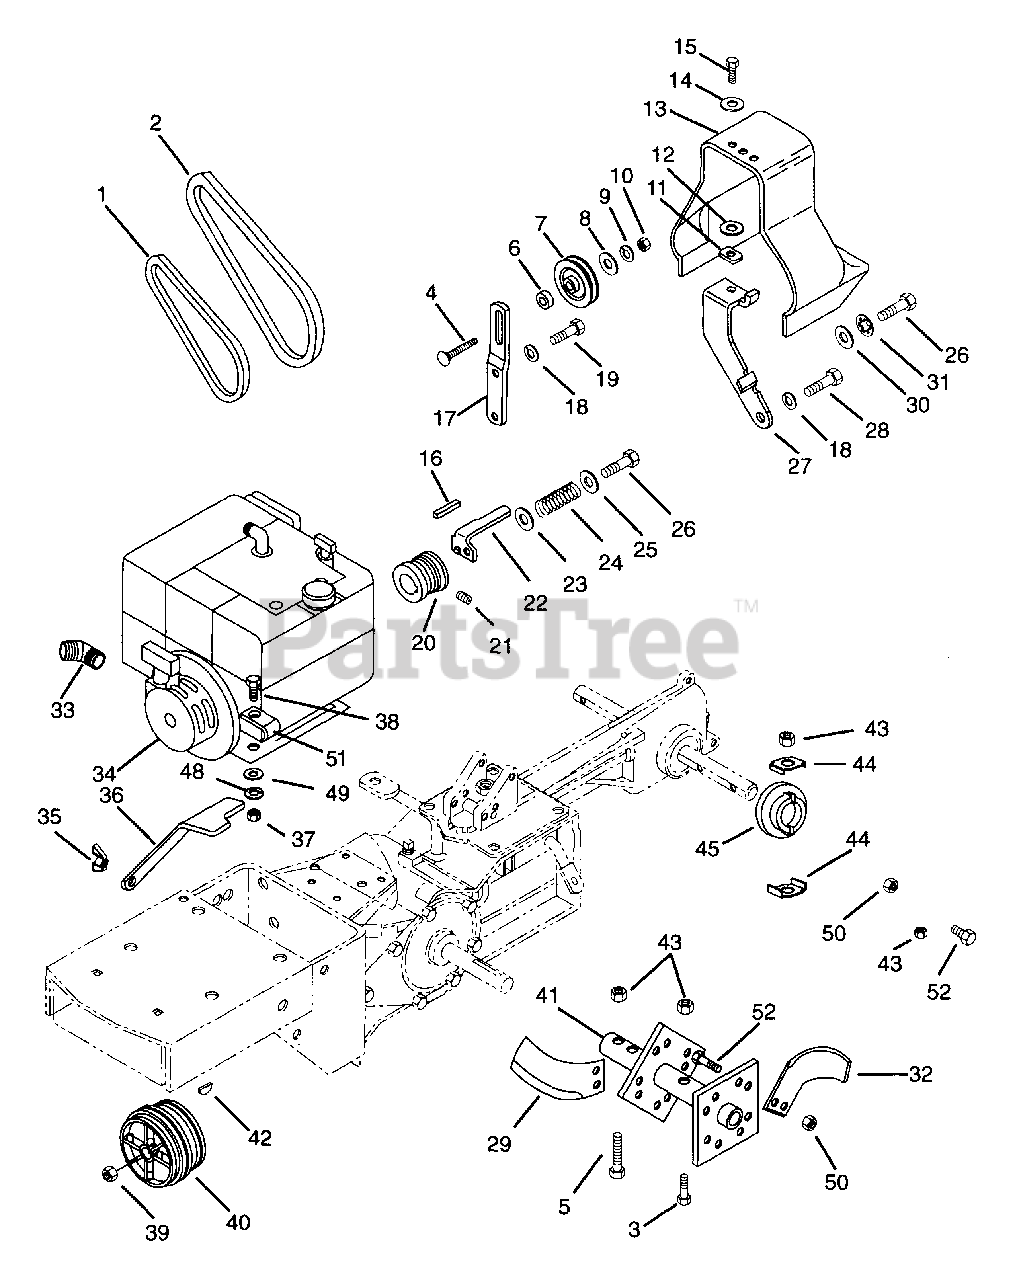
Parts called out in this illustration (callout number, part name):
1	V-BELT, SAE 380-RAW EDGE (SET)
2	V-BELT, 3L-COGGED
3	BLT-HEX .38-16X2.00 GR8
4	BLT-RDHDSQNK .31-18X1.38SHT PL
5	BLT-HEX .38-16X2.75 GR8
6	SPCR, BRG .315X.50X.688X.281
7	IDLER
8	WSHR-FL-STL .38X.875X.083 PL
9	WSHR-LK .312X.097 PL HVY
10	NUT-HEX .312-18
11	NUT-SPEED U-TYPE .250-20
12	NUT-RETNR
13	WLDMT,SHAFT UPPER STEERING
14	WSHR-FL-STL .250X.562X.049 PL
15	BLT-HEX .25-20X.50 PL GR5
16	KEY-SQ .25 X 1.25 X .25 SAE
17	REVERSE IDLER BRACKET
18	WSHR-LK .375X.115 HVY PL
19	BLT-HEX .38-16X.75 PL GR2
20	ENGINE SHEAVE
21	SCR-SET .32-18X.38 SKHCUPNL OH
22	BELT FINGER
23	WSHR-FL-STL .406X1.125X.125 PL
24	SG-COMP .125X.68X1.62
25	WSHR-FL-STL.406X.812X.065PL
26	BLT-HEX .38-16X2.00 PL GR2
27	BELT COVER BRACKET
28	BLT-HEX .38-16X.63 PL GR2
29	R KNIFE TINE
30	WSHR-FL-STL .323X.625X.062 PL
31	WSHR-LK-INT .313X.030 PL
32	L KNIFE TINE
33	MANUAL, OWNER'S - RT 5018
34	ENGINE, B&S 8HP MODEL 196432
35	NUT-WING W/INSERT .312 - 18
36	BELT FINGER
37	NUT-HEX .312-18
38	BLT-HEX .31-18X2.00 PL GR5
39	NUT-LK-CTR .75-16 PL
40	DRIVE SHEAVE
41	INNER TINE HUB
42	KEY-FTHR .188X1.25X.187 SAE
43	NUT-LK TOP .375-16 GR C YWZC
45	DUST CAP
46	NUT-LK-TOP .437-14 GR C PL
47	BLT-HEX .44-14X1.00 GR5
48	WSHR-LK .313X.078 PL MED
49	WSHR-FL-STL .328X.875X.062 PL
50	NUT-LK-TOP .437-14 GR C PL
51	NUT-LK-TOP .437-14 GR C PL
52	BLT-HEX .44-14X1.00 GR5
